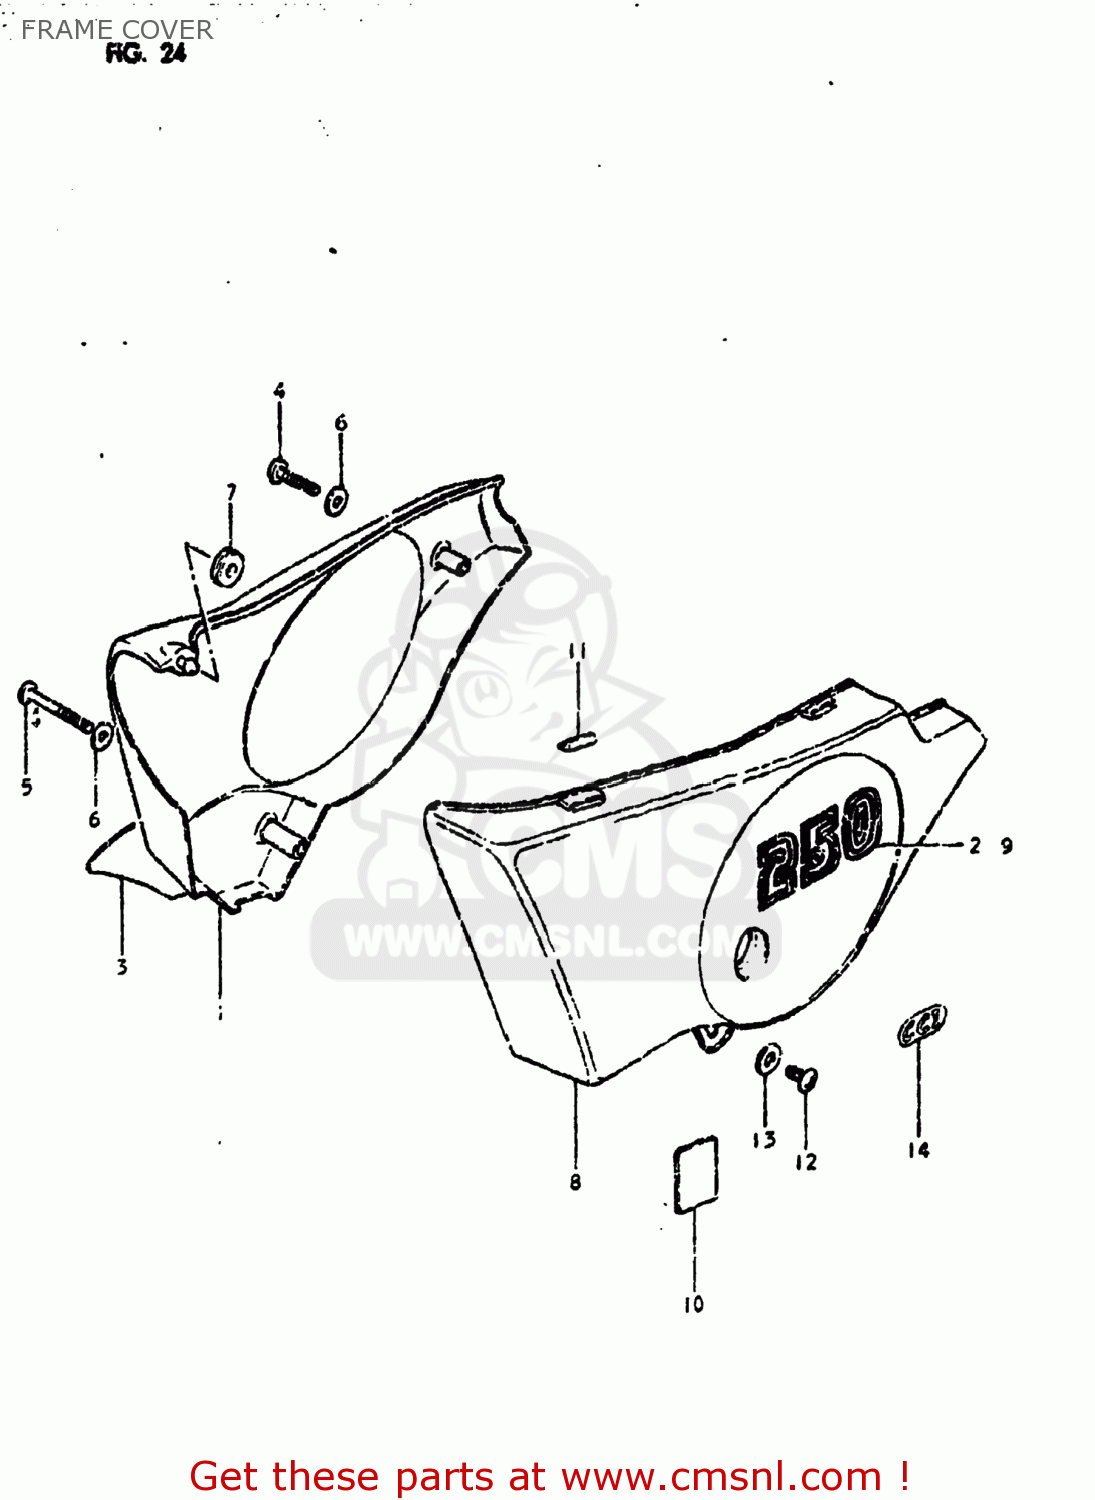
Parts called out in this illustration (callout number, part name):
1	COVER,FRAME,RIGHT
2	EMBLEM
3	EMBLEM,FRAME COVER,RIGHT
4	SCREW
5	SCREW
6	WASHER
7	CUSHION
8	COVER,FRAME,LEFT
9	EMBLEM,FRAME COVER
10	PROTECTOR(170X95X3.0)
11	CUSHION,FRAME COVER
12	SCREW 6X12
13	WASHER
14	EMBLEM,CCIS
